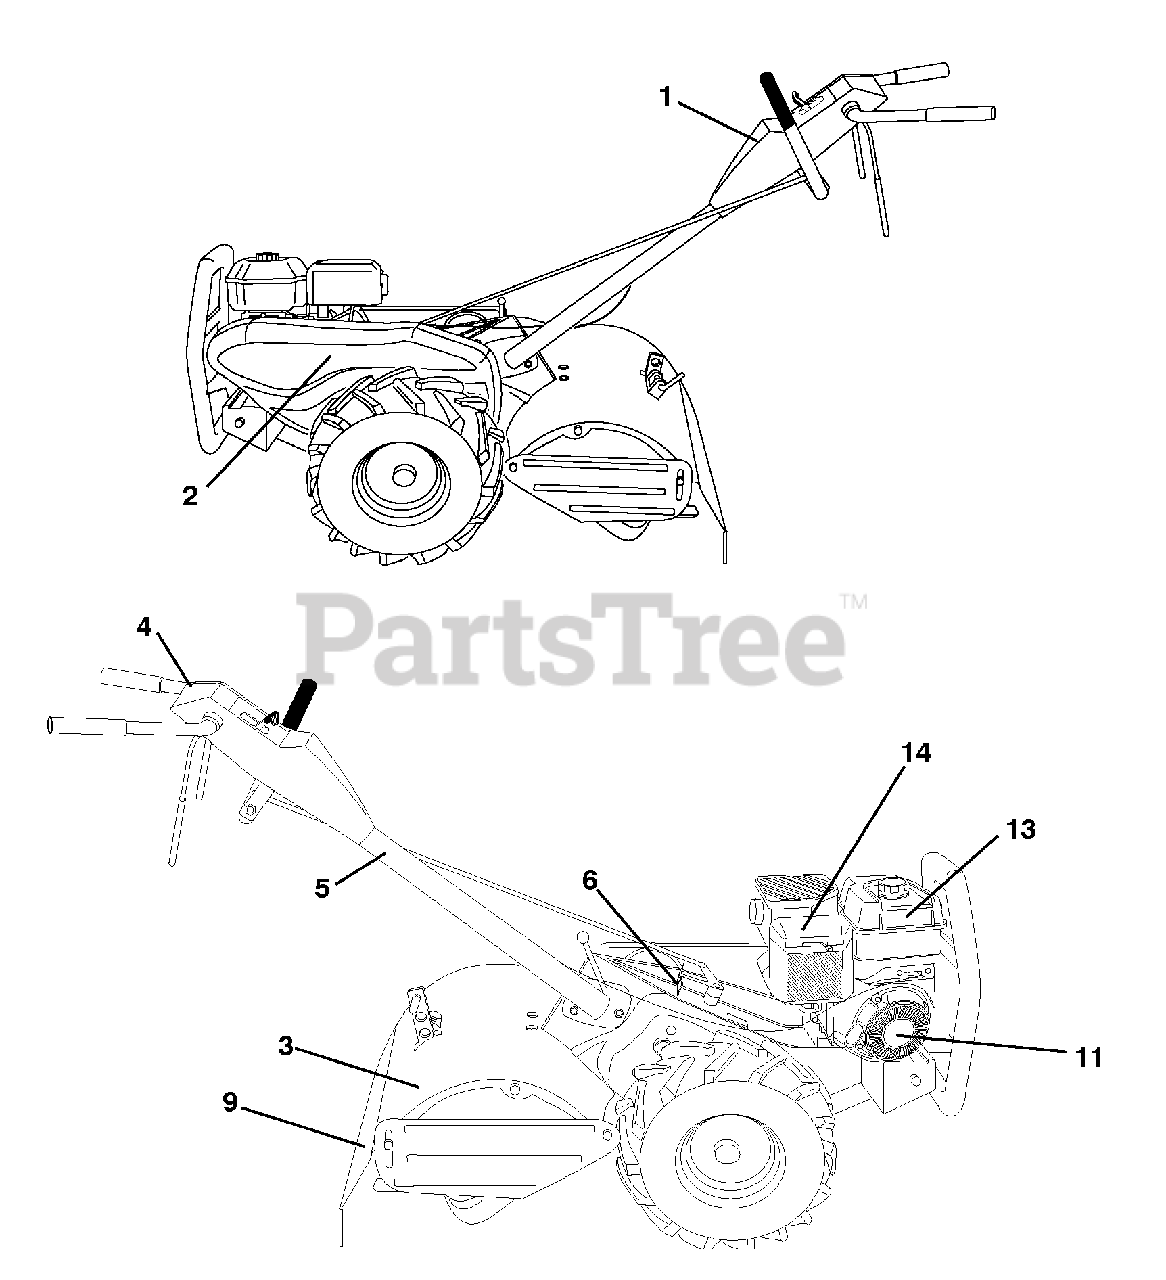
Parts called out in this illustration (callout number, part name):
1	Decal, CNTRL PNL
2	Decal, Blt Grd
3	Decal, Warning
4	Decal, Instruction, Tilling
5	Decal, Hand Placement
6	Decal, Shift Indicator
7	Decal, Caution
9	Decal, Warning, Rotating Tines
11	Decal, Rewind
13	Decal, B&S Tank
14	Decal, B&S, Air Cleaner
14	Manual, Operator's, English/French
14	Manual, Repair Parts, English/French
